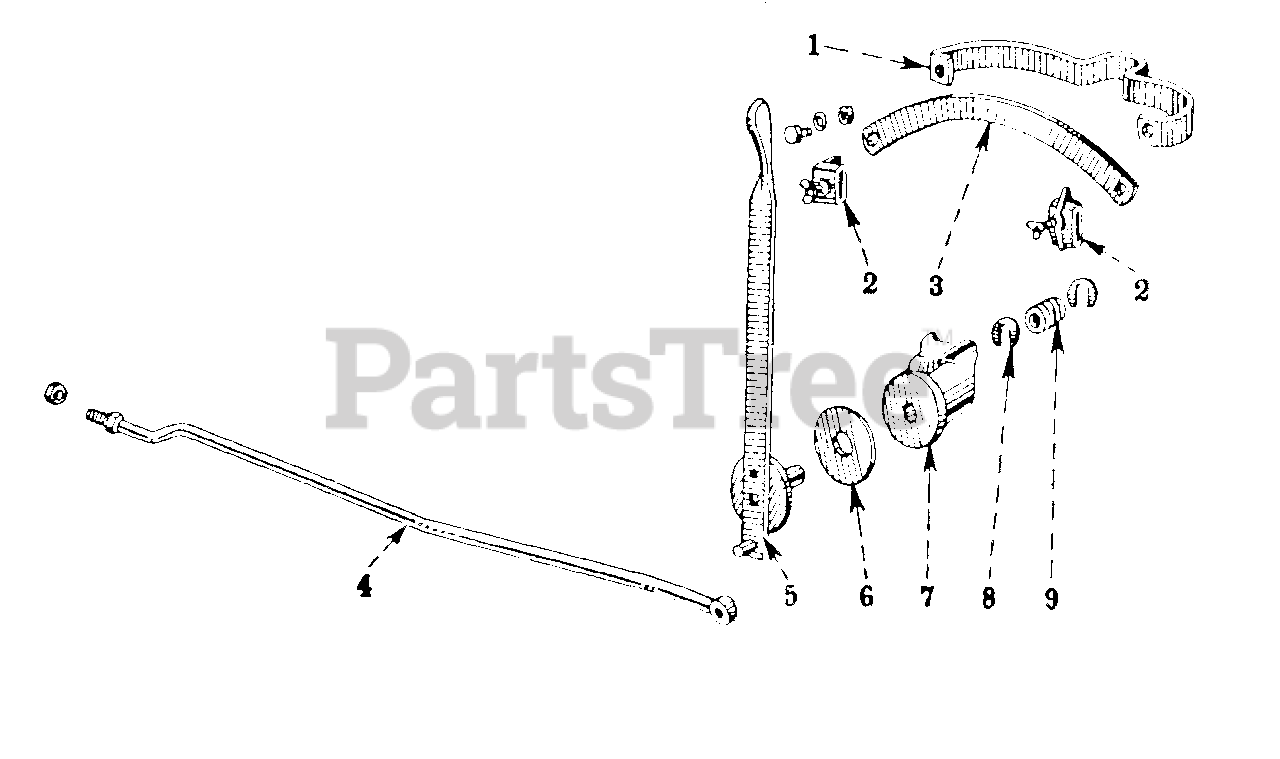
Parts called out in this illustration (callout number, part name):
1	SUPPORT, HAND CONTROL QUADRANT
2	INDICATOR ASSY, STOP
3	QUADRANT, HAND CONTROL LEVER
5	LEVER ASSY, HAND CONTROL
6	DISC, HAND CONTROL LEVER FRICTION
7	BRACKET, HAND CONTROL LEVER
8	RETAINER, HAND CONTROL LEVER FRICTION SPRING
9	SPRING, HAND CONTROL LEVER FRICTION
